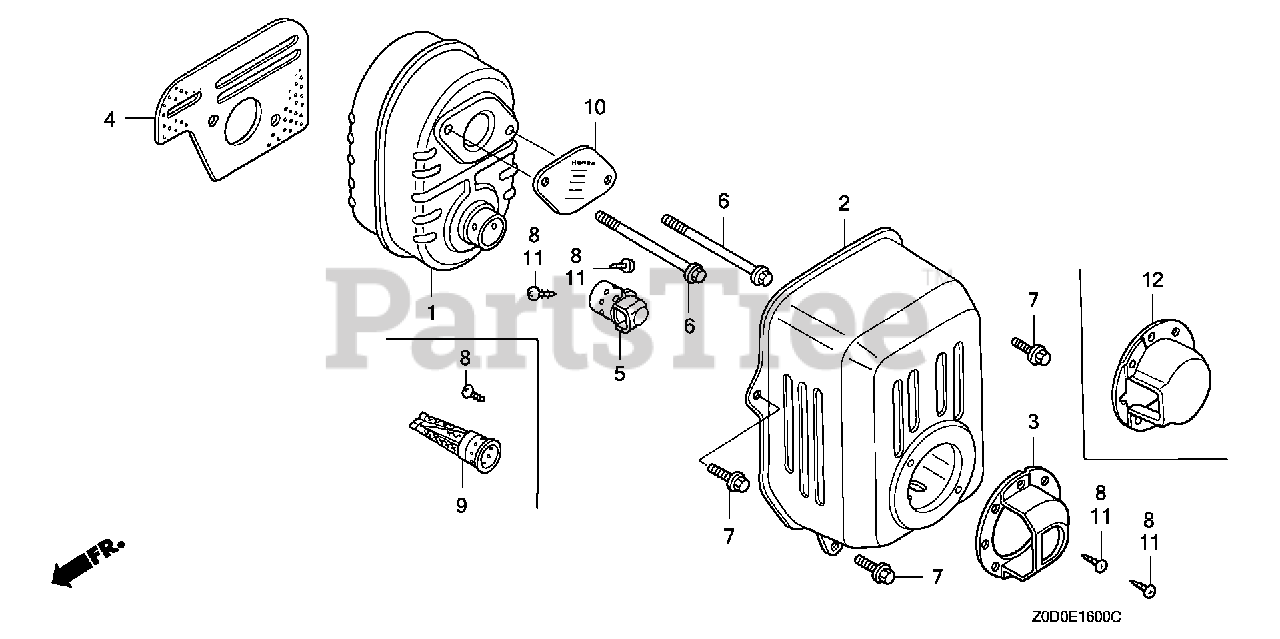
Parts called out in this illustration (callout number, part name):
2	PROTECTOR, MUFFLER
3	CAP, MUFFLER
4	GASKET, MUFFLER
5	DEFLECTOR, MUFFLER
6	BOLT, FLANGE (6X79) (CT200)
7	BOLT, FLANGE (6X14) (CT200)
8	SCREW, TAPPING (4X6)
9	ARRESTER, SPARK
10	PLATE, ARRESTER NUMBER
